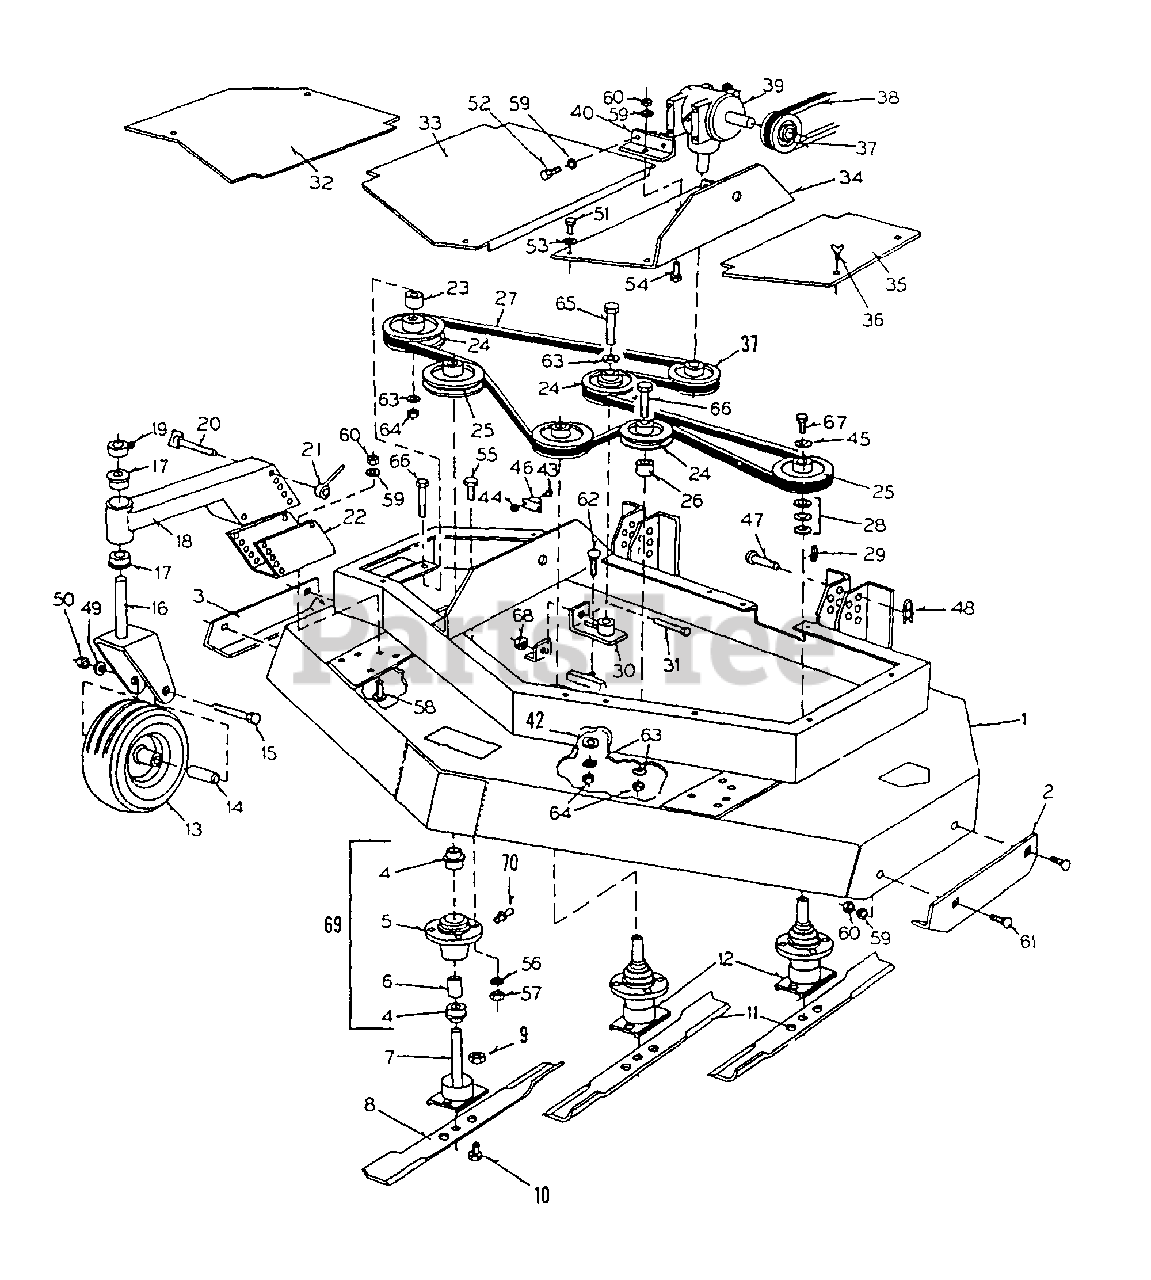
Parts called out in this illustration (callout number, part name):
1	DECK - rear discharge 52"
2	SHOE - skid L.H.
3	SHOE - skid R.H.
4	BEARING - spindle 7/8
5	HOUSING - spindle
6	SPACER - spindle
7	SHAFT - spindle L.H. rotation
8	BLADE - L.H. rotation
9	NUT - 3/8" - 16 lock
10	BOLT - 3/8" - 16 x 1"
11	BLADE - R.H. rotation
12	SHAFT - spindle
14	AXLE - gauge wheel
15	BOLT - 1/2" - 13 x 6-1/2"
16	FORK - gauge wheel
18	MOUNT - gauge wheel
19	COLLAR - set 1,"
20	BOLT - wing 3/8" - 16 x 4-1/2"
21	NUT - gauge wheel handle 3/8" - 16
22	BRACKET - gauge wheel mount
23	SPACER - idler pulley
24	PULLEY - idler 5"
25	PULLEY - spindle 4-1/2"
26	SPACER - idler pulley
28	WASHER - spacer
29	KEY - 3/16" x 3/16" x 1"
30	TIGHTENER - belt
31	BOLT - 1/4" - 20 x 4"
33	COVER - center
34	MOUNT - gear box
36	SCREW - thumb 1/4" - 20 x 1/2"
37	PULLEY - gear box
39	GEAR BOX - angle drive
40	ANGLE - gear box mount
42	WASHER - 3/8"
43	SCREW - #10 - 32 x 1/2"
44	NUT - lock #10 - 32
45	WASHER - spindle 3/8" hardened
46	BREAKER - circuit 10 amp.
47	PIN - clevis 1/2" x 1-1/2"
48	PIN - cotter, hair
49	LOCKWASHER - 1/2"
50	NUT - 1/2" - 13
51	BOLT - 1/4" - 20 x 3/4"
52	BOLT - 5/16" - 18 x 1"
53	LOCKWASHER - 1/4"
54	BOLT - 5/16" - 18 x 3/4"
55	BOLT - 7/16" - 14 x 1-1/4"
56	LOCKWASHER - 7/16"
57	NUT - 7/16" - 14
58	BOLT - carriage 5/16" - 18 x 1"
59	LOCKWASHER - 5/16"
60	NUT - 5/16"
61	BOLT - carriage 5/16" - 18 x 3/4"
62	BOLT - carriage 3/8" - 16 x 1"
63	LOCKWASHER - 3/8"
64	NUT - 3/8" - 16
65	BOLT - 3/8" - 16 x 1-1/4"
66	BOLT - 3/8" - 16 x 2-1/2
67	BOLT - 3/8" - 24 x 1-1/4"
68	NUT - lock 1/4" - 20
69	HOUSING ASSEMBLY - spindle
70	FITTING - grease 1/4" - 28
